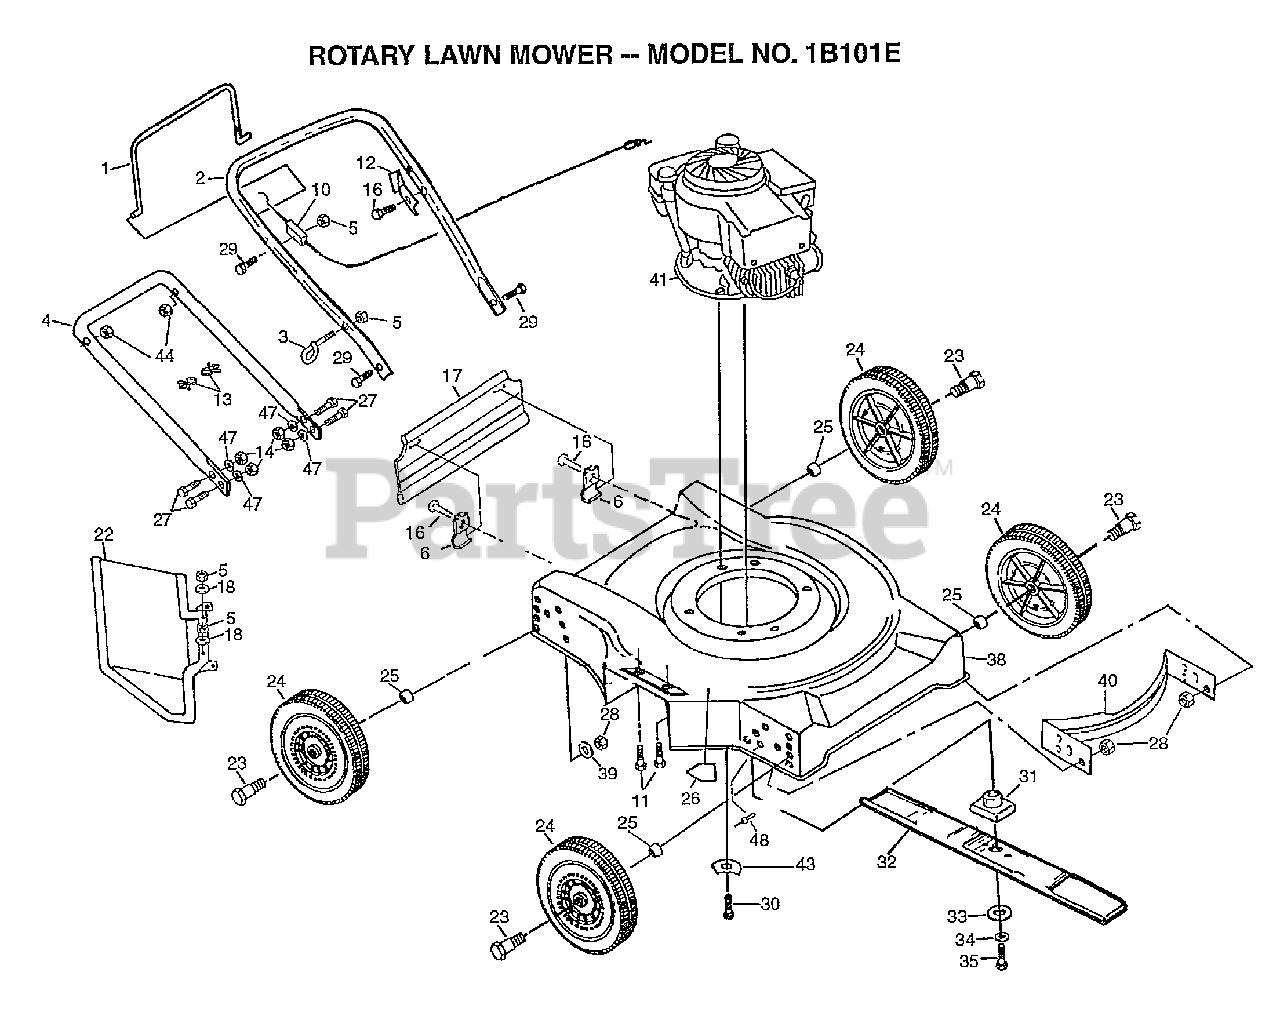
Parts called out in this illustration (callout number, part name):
1	CONTROL BAR PM
2	UPPER HANDLE
3	ROPE GUIDE
4	HANDLE LWR PM
6	"BRKT,DEFL PM"
10	CABLE.ZONE.CONTRO
11	BOLT LT
12	"BRKT,UPSTOP"
13	CABLE CLIP PM
14	LOCKNUT
16	TAPPING SCREW
17	SKIRT.REAR.20RD.
22	"GRD,DISCHARGE"
23	AXLE BOLT
24	WHEEL ASSY
26	DECAL HYT
28	LOCKNUT PM
29	BOLT 1/4-20-1 1/2
30	BOLT.ENG.3/8-16
31	BLADE ADAPTOR
32	BLADE.20.MULCH.AY
33	"WASHER,HARDEN"
34	LOCKWASHER
35	SCREW
47	STEEL WASHER
48	BLIND RIVET
